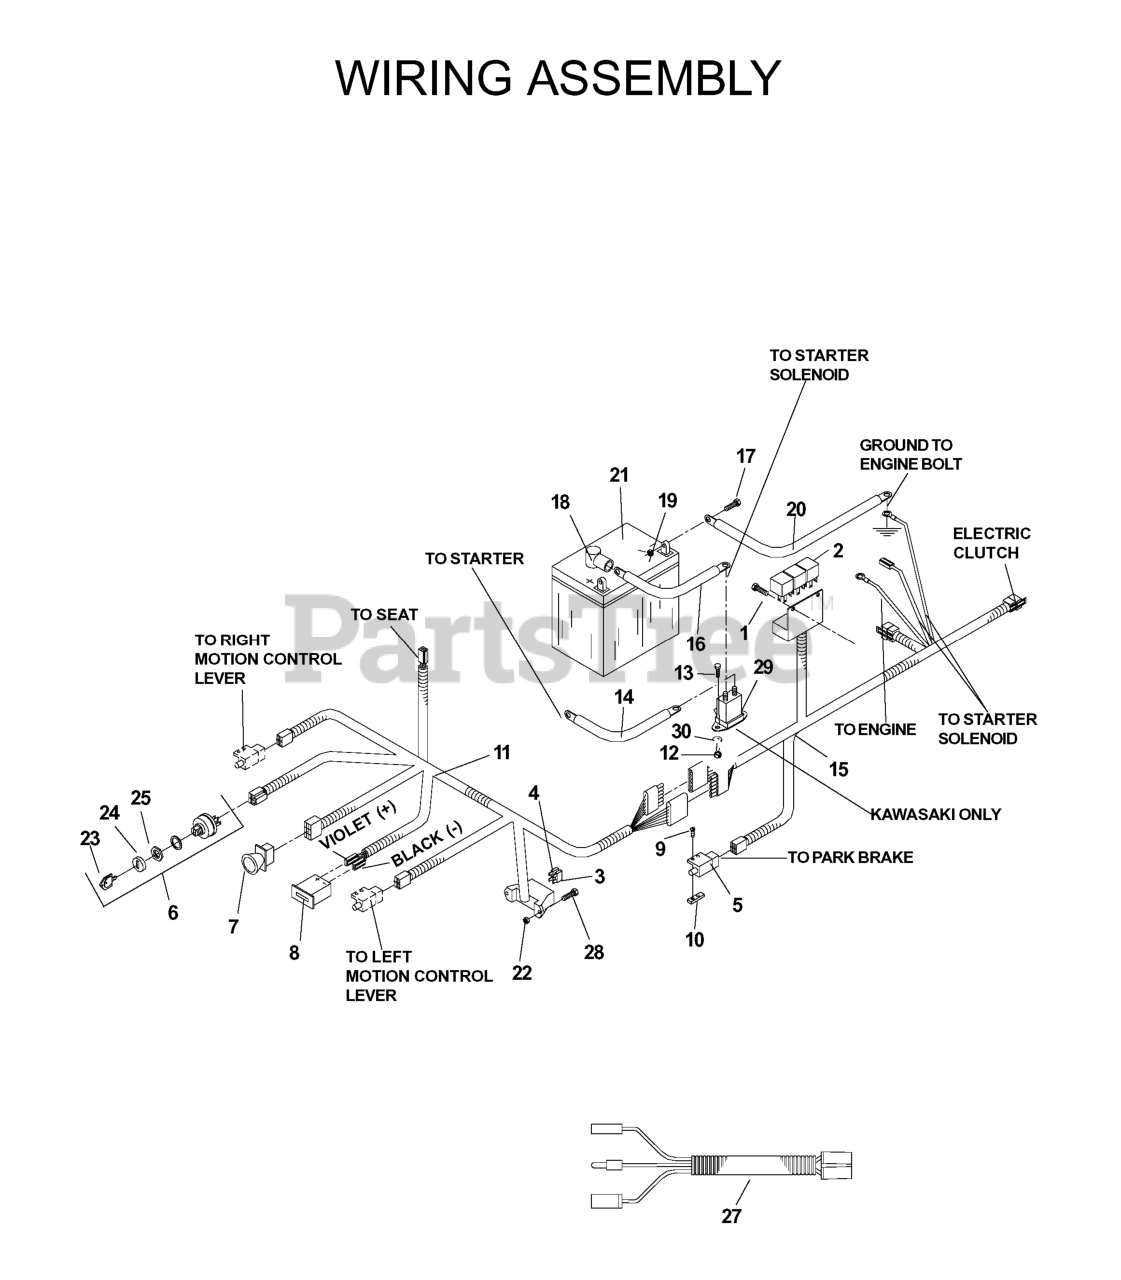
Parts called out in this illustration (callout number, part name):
1	SCREW #10 X 1/2 SELF TAPPING
3	FUSE, 7.5 AMP 32 VOLT ATO
4	FUSE, 20 AMP 32 VOLT ATO
5	SWITCH, INTERLOCK
6	IGNITION SWITCH KIT
7	RP.SWITCH, BLADE
8	DIGITAL HOUR METER
9	SCREW #10-24 X 5/8
10	TAPPED PLATE
11	CONSOLE HARNESS
12	NUT 1/4C CENTERLOCK
13	HCS 1/4C X 5/8
14	POST.CABLE LONG
15	FRAMES HARNESS
16	CABLE POSITIVE, LONG
17	HCS 5/16C X 3/4
19	NUT 5/16C CENTERLOCK
20	CABLE-NEGATIVE
21	BATTERY WET NOT SELLABLE
22	NUT 10-24 NYLOC
23	KEY-PADDED
24	CAP IGNITION NUT
25	DNO IGNITION NUT
27	KAW PIGTAIL
28	SCREW, #1--24 X 1/2 SLOTTED
30	WASHER 1/4 INT TOOTH
539102757	CABLE POSITIVE
